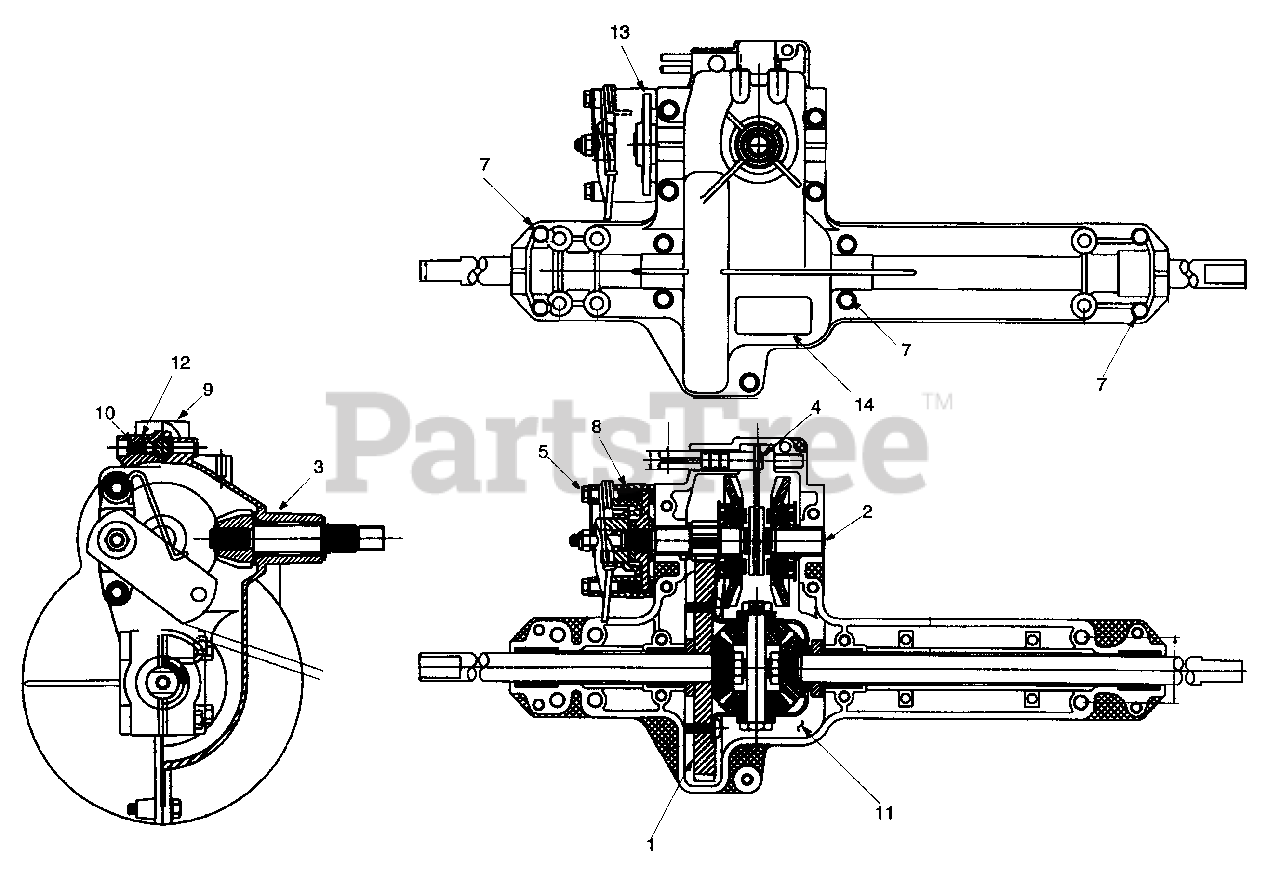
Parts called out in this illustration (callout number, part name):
1	Differential Assembly: Single Speed
2	Drive Shaft assembly: LH Brake
3	Upper Housing Assembly
4	Detent Shaft Assembly
5	Brake Yoke assembly: LH
7	Hex Washer Hd. TT Screw 1/4-20 x 1.65
8	Brake Puck
9	Lower Housing
10	Spring Detent
11	Grease
12	Ball Detent
13	Brake Disc
14	Label
